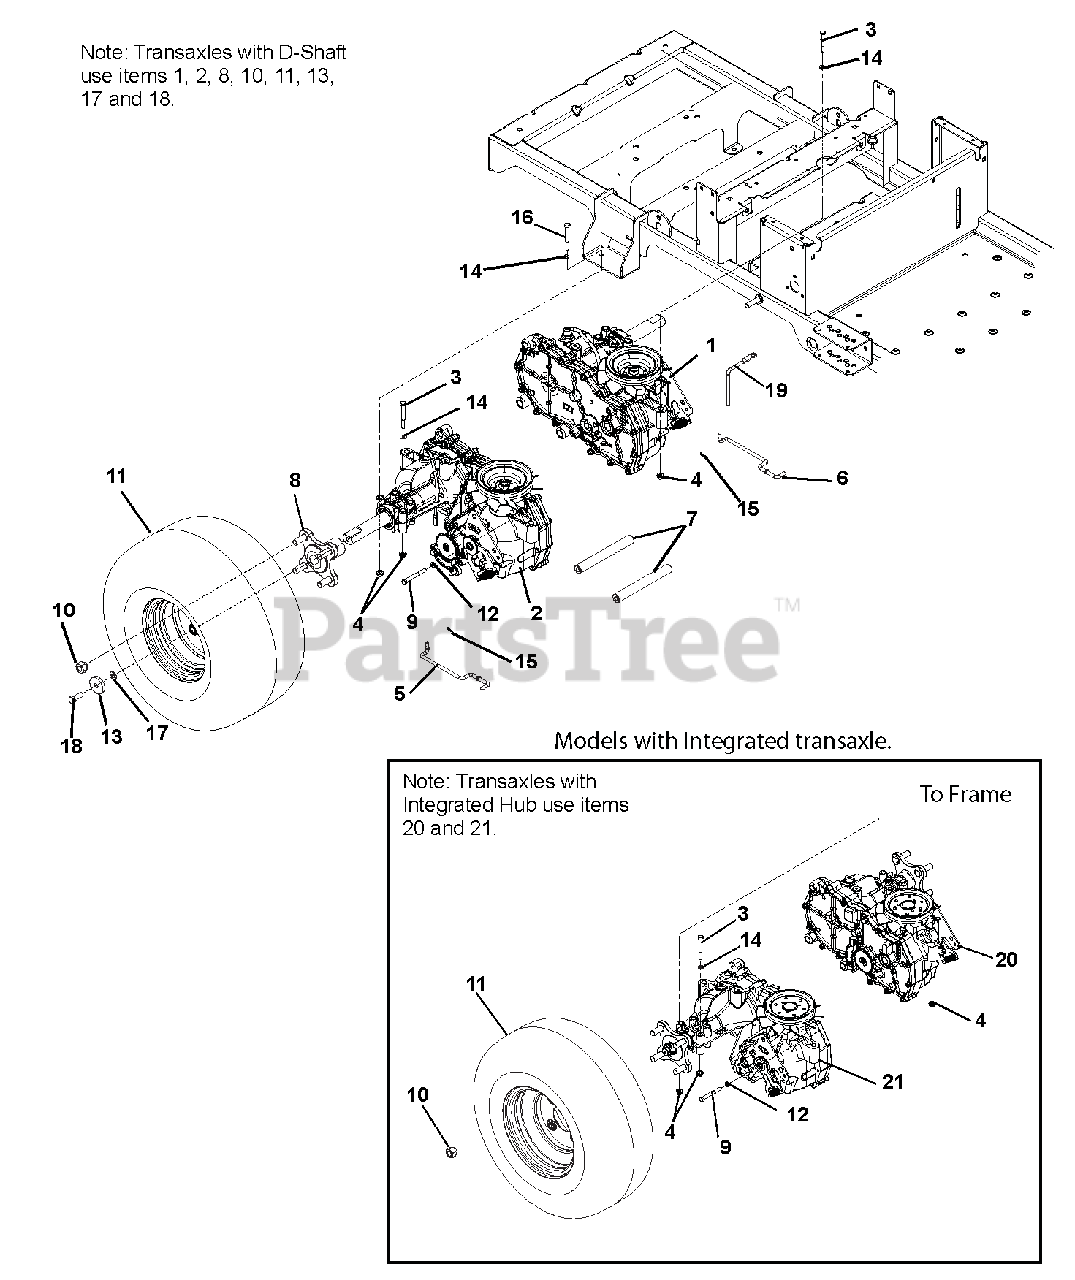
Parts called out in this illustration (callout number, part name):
1	TRANSAXLE, LH EZT D-SHAFT
2	TRANSAXLE, RH EZT D-SHAFT
3	@BLT-HEX .31-18X2.25 GR5 YWZC
4	@NUT-LK-NYL-FLG .31-18 YWZC
5	DUMPVALVE, RH LCZ
6	DUMPVALVE, LH LCZ
7	SHAFT, CROSS BRACE
8	ASM, WHEEL HUB
9	@BLT-HEX .38-16X2.50 GR5 YWZC
10	WHEEL NUT .500-20 YZ
11	TIRE/WHEEL ASSY, 18X8.50-8 CTR
12	WSHR-FL-STL .406X1.00X.188 YWZ
13	WSHR,FLT STL.406X1.50X.245YWZC
14	@WSHR-FL-STL.38X.875X.083 YWZC
15	PIN-HAIR INT .06X.18X.77
16	@BLT-HEX .31-18X2.75 GR5 YWZC
17	@WSHR-LK .38X.094 REG YWZC
18	@BLT-HEX .38-16X1.00 GR5 YWZC
19	BELT FINGER
20	TRANSAXLE, LH EZT SHORT
21	TRANSAXLE, RH EZT SHORT
